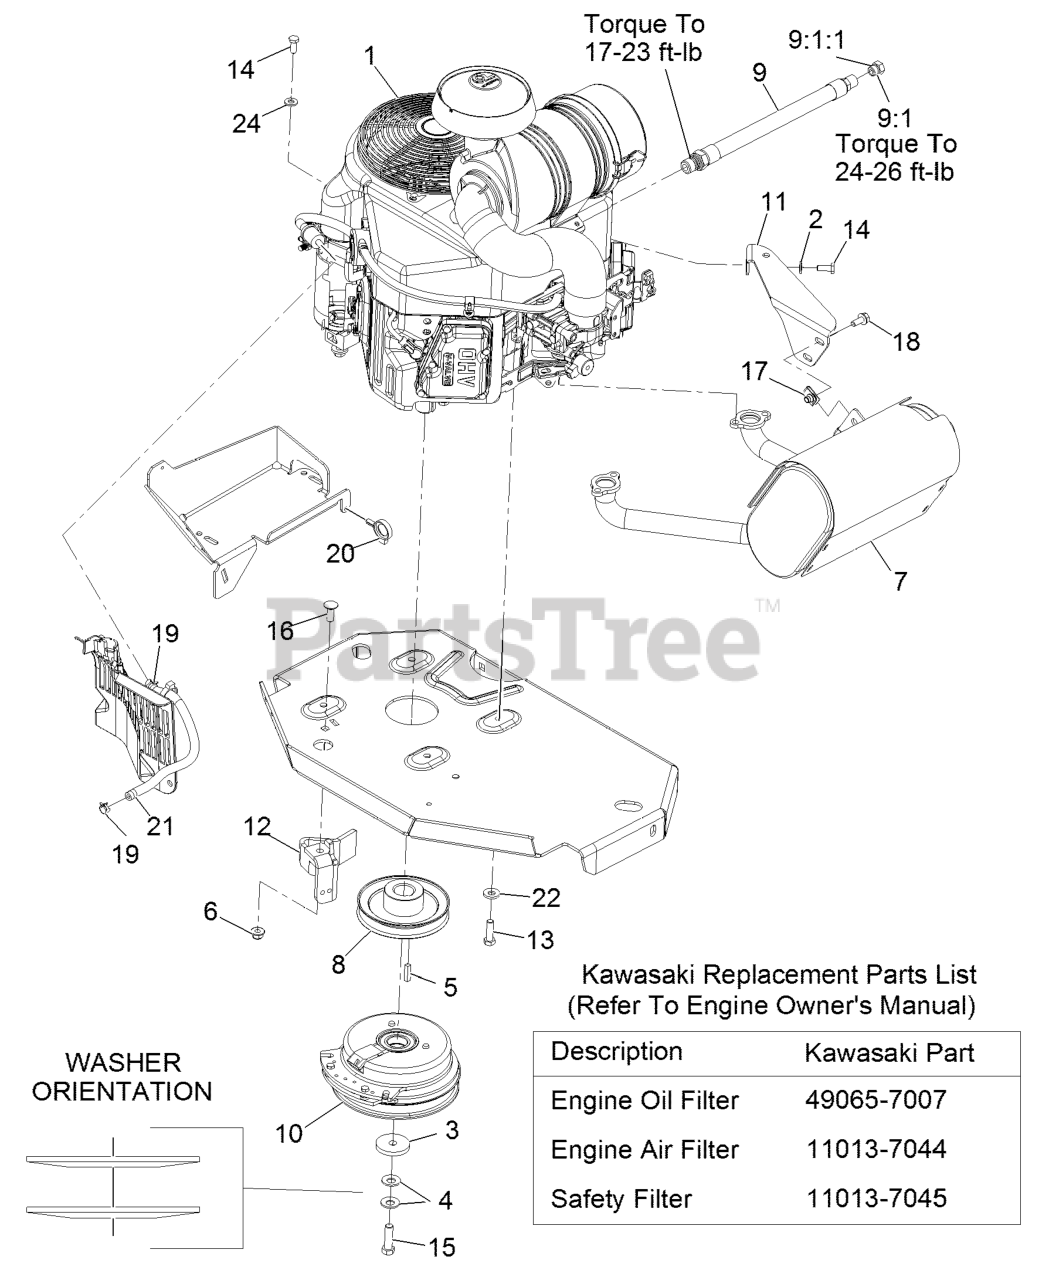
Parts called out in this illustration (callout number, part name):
2	WASHER-SPRING
3	WASHER-CLUTCH
4	WASHER-SPRING
6	NUT-HF, NI
7	MUFFLER
8	SHEAVE-PUMP, DRIVE
9	ENGINE OIL DRAIN HOSE ASM
9:1	PLUG-HH
9:1:1	O-RING
11	BRACKET-MUFFLER
12	CLUTCH-ANCHOR
13	SCREW-HH
14	SCREW-HH
15	SCREW-HH 7/16-20 X 1 1/2 W/LOCTITE
16	SCREW-CARR
18	SCREW-HHF
19	CLAMP-HOSE
20	CLAMP-HOSE
21	HOSE-FUEL
22	WASHER-BELLEVILLE
24	WASHER-PLAIN
